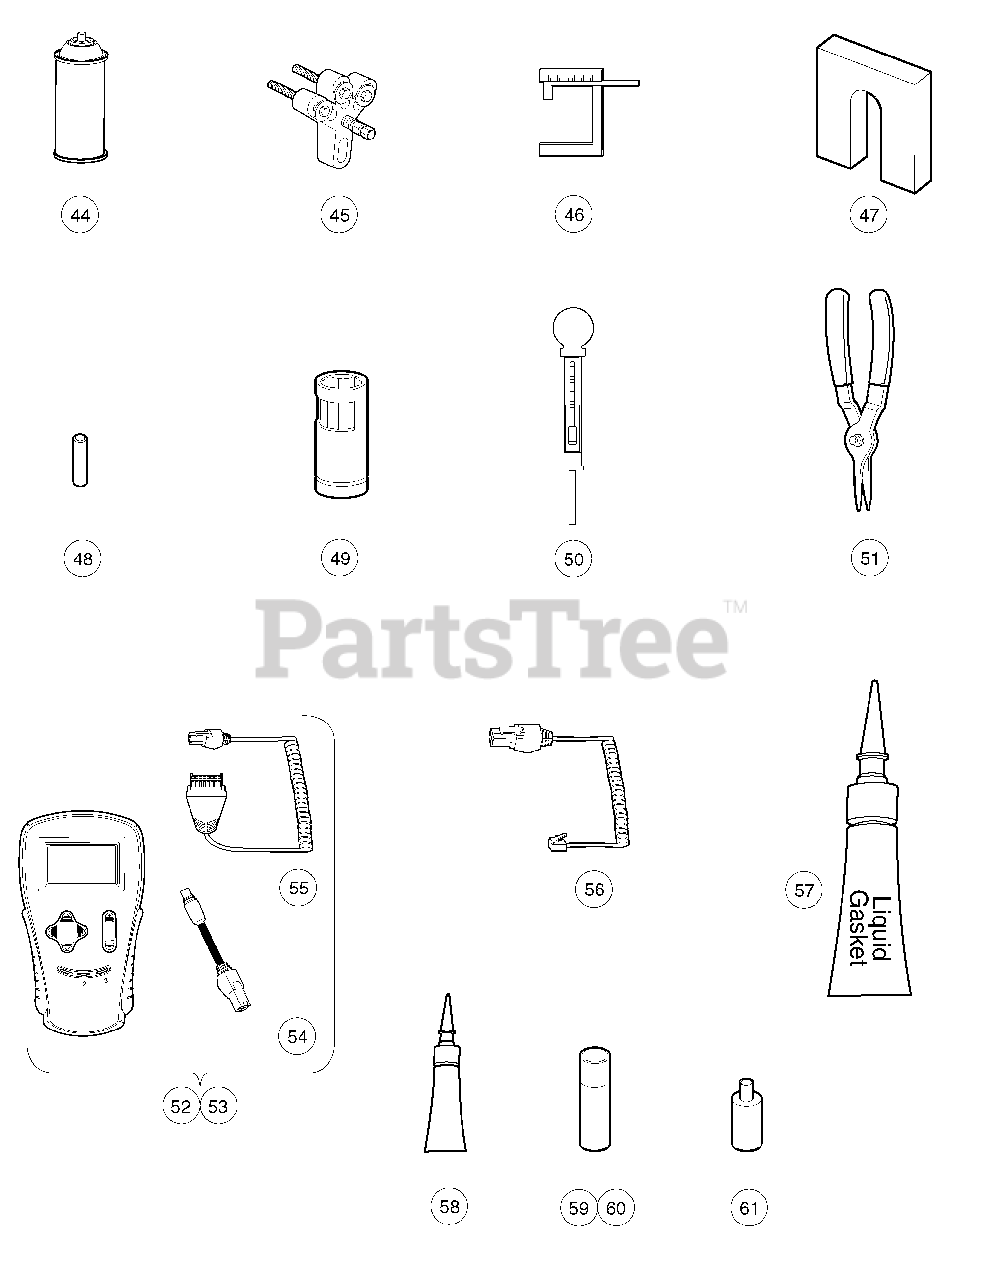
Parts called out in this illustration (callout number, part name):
44	Dry Moly Lubricant
45	Flywheel Puller Kit
46	Gauge, Carburetor Float Level
47	Gear Yoke
48	Governor Shaft Installation Tool
49	Hydraulic Brake Adjuster (for Turf/CA 272/472, Pioneer/XRT 1200, Bobcat 2100, HUV 4213)
50	Hydrometer
51	Internal Retaining Ring Pliers
52	IQ Display Module (IQDM) Kit (IQ System and IQ Plus vehicles)
53	IQ Display Module (IQDM-P) Kit (IQ System and IQ Plus vehicles)
54	Adaptor, Cable
55	IQDM Series 2 Cable
56	IQDM Series 1 Cable (replacement)
57	Liquid Gasket (transaxle case)
58	Moly-Teflon Lubricant (4-oz. (113-gram) tube)
59	Paint, Touch-Up - Beige
59	Paint, Touch-Up - Black
59	Paint, Touch-Up - Burgundy
59	Paint, Touch-Up - Classic Blue (Navy)
59	Paint, Touch-Up - Dark Gray
59	Paint, Touch-Up - Dark Green
59	Paint, Touch-Up - Gray
59	Paint, Touch-Up - Red
59	Paint, Touch-Up - Royal Blue (Pacific Blue)
59	Paint, Touch-Up - White
60	Paint, Precedent Underbody - Gray
61	Paint Pen, Touch-Up, Precedent Underbody - Black
